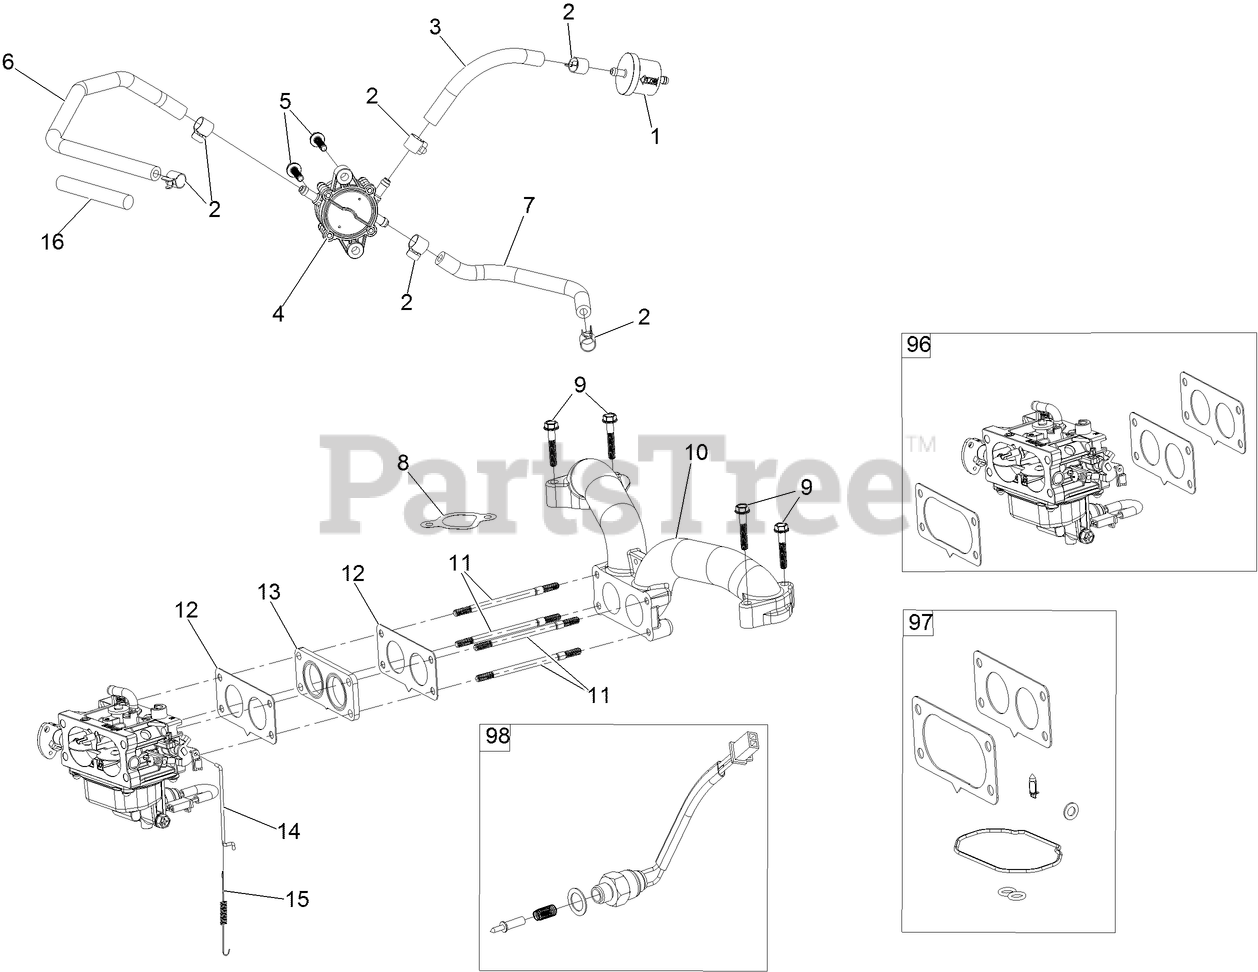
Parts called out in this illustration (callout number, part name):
1	FILTER-FUEL
2	CLAMP-FUEL LINE
3	LINE-FUEL
4	PUMP-FUEL
5	SCREW-HHF
6	HOSE-FUEL
7	HOSE-FUEL
8	GASKET-INTAKE
9	SCREW-HHF
10	MANIFOLD-INTAKE
12	GASKET-CARBURETOR
13	INSULATOR-CARBURETOR
14	LINKAGE-THROTTLE
15	SPRING-RETURN, THROTTLE
16	SLEEVE-FUEL LINE PROTECTOR
96	CARBURETOR REPLACEMENT KIT
97	CARBURETOR REPAIR KIT
98	SOLENOID KIT
